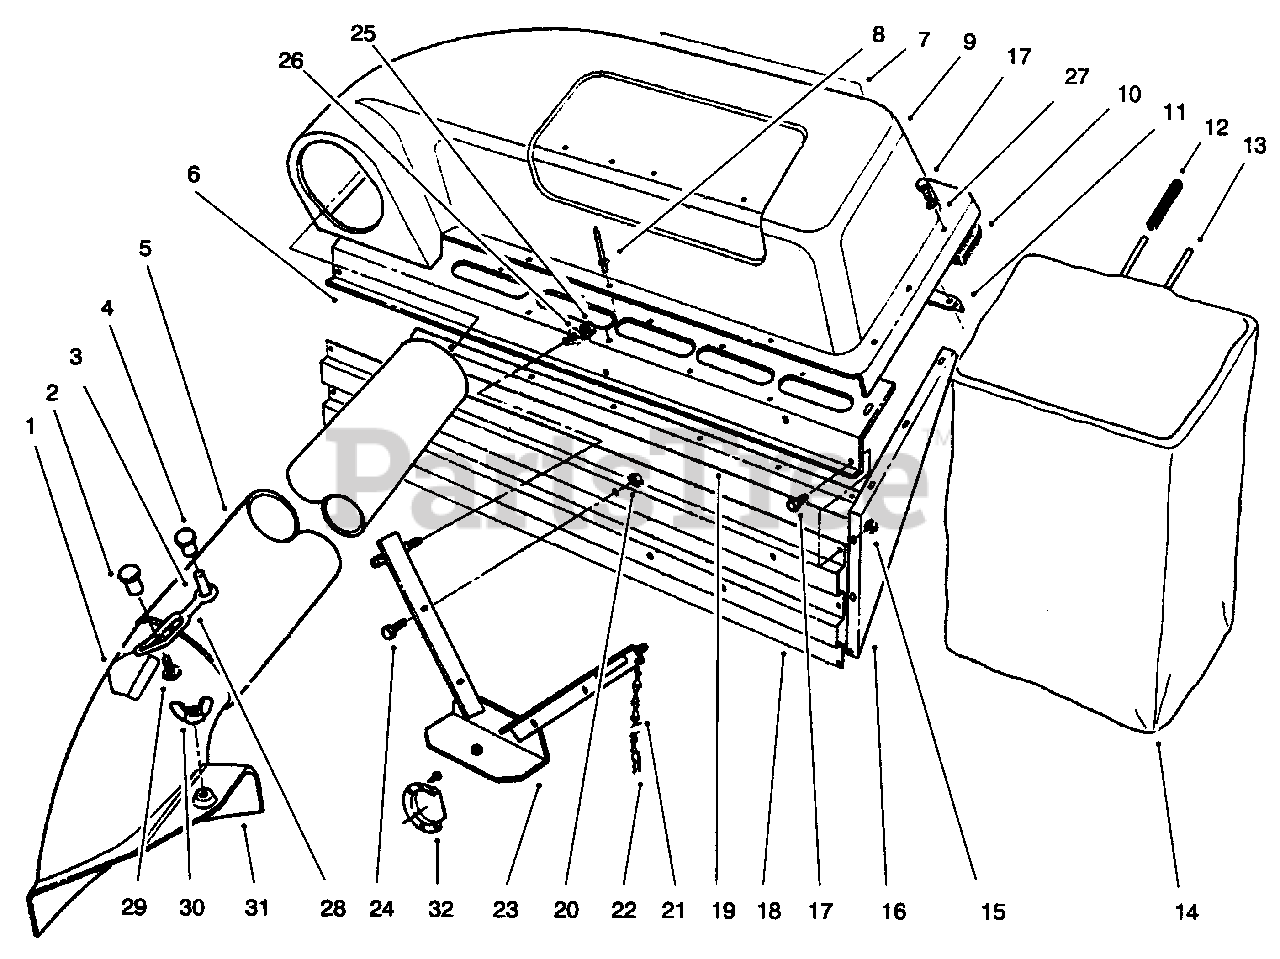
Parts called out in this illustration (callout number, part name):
1	Decal-Chute
4	Fastner-Panel
7	Decal-Twin Bagger
8	Rivet-Pop
10	Seal-Foam
11	Bracket-Frame, Bag
12	Grip-Handle
13	Frame-Bag
15	Nut-Lock
16	Plate-Side
17	Screw-Cap Hex. Hd.
18	Shield-Muffler
19	Channel-Support, Bag
20	Nut-Lock
22	Pin-Hair, Cotter
23	V-Bracket
24	Screw-Cap Hex. Hd.
25	Nut-Lock
26	Washer-Flat
27	Washer-Flat
28	Retainer-Duct
31	Assembly-Chute (Incl. Ref. #1, 2 & 29)
32	Deflector-Muffler
